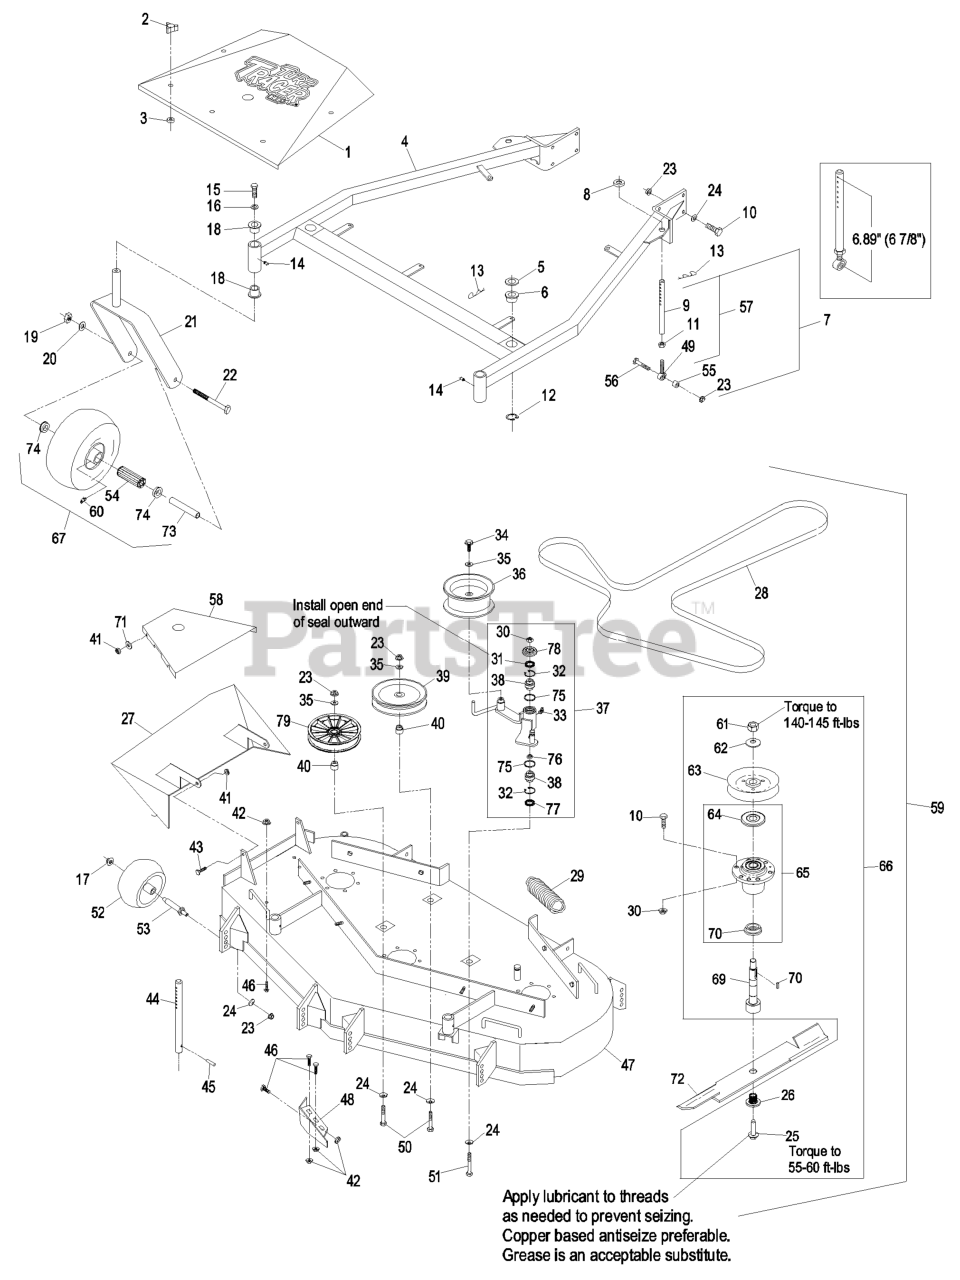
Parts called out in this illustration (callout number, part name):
2	KNOB-3 PRONG
4	SUPPORT,DECK W/BUSHINGS
5	SPACER-DECK SUPPORT
6	BUSHING-DECK
7	KIT,SUPPORT LINK W/PIN
9	LINK,SUPPORT
10	SCREW-HH
11	NUT-HJ
12	RING-RETAINING
13	PIN,HAIR COTTER
14	FITTING-GREASE
15	SCREW-HH
16	WASHER-LOCK
18	BEARING-FLANGED
19	NUT-HH
20	WASHER-LOCK
22	SCREW-HH
23	NUT-HHF, WHIZ
24	WASHER-BELLEVILLE
26	BUSHING,SPLINED
27	WLD,CHUTE DISCHARGE
28	BELT,DECK DRIVE
30	NUT-LOCK, NI
31	SEAL-LIP, SINGLE
32	RING-SNAP
33	FITTING-GREASE, 90 DEG
34	SCREW-HHF
35	WASHER-FLAT
37	KIT, DECK IDLER TTHP48&52
38	BEARING-SPHERICAL
39	PULLEY-IDLER
40	BUSHING-IDLER
41	NUT-LOCK, NI
43	SCREW-HH
44	ROD,DECK SUPPORT
46	SCREW-HH
47	ASM,DECK W/DECALS TTHP52
48	WLD,BAFFLE DISCHARGE
49	BALLJOINT
50	SCREW-HH
51	SCREW-HH
52	ROLLER-SCALP, ANTI
54	BEARING
56	SCREW-HH
58	SHIELD,SIDE BELT 52
59	Asm, Deck Complete
60	FITTING-GREASE
63	SHEAVE,W/HUB 5.72
64	GUARD-BEARING, TOP
65	KIT, CUTTER HOUSING
66	ASM, CUTTER HSG
67	KIT, SP CASTER WHEEL REPL
68	SPACER-GUARD, BOTTOM
69	KIT, SPLINED SPINDLE 103-
70	KEY-RECTANGLE
71	WASHER-FLAT
74	BUSHING
77	SEAL-LIP, DOUBLE
78	GUARD-TOP
79	PULLEY,IDLER 5"
